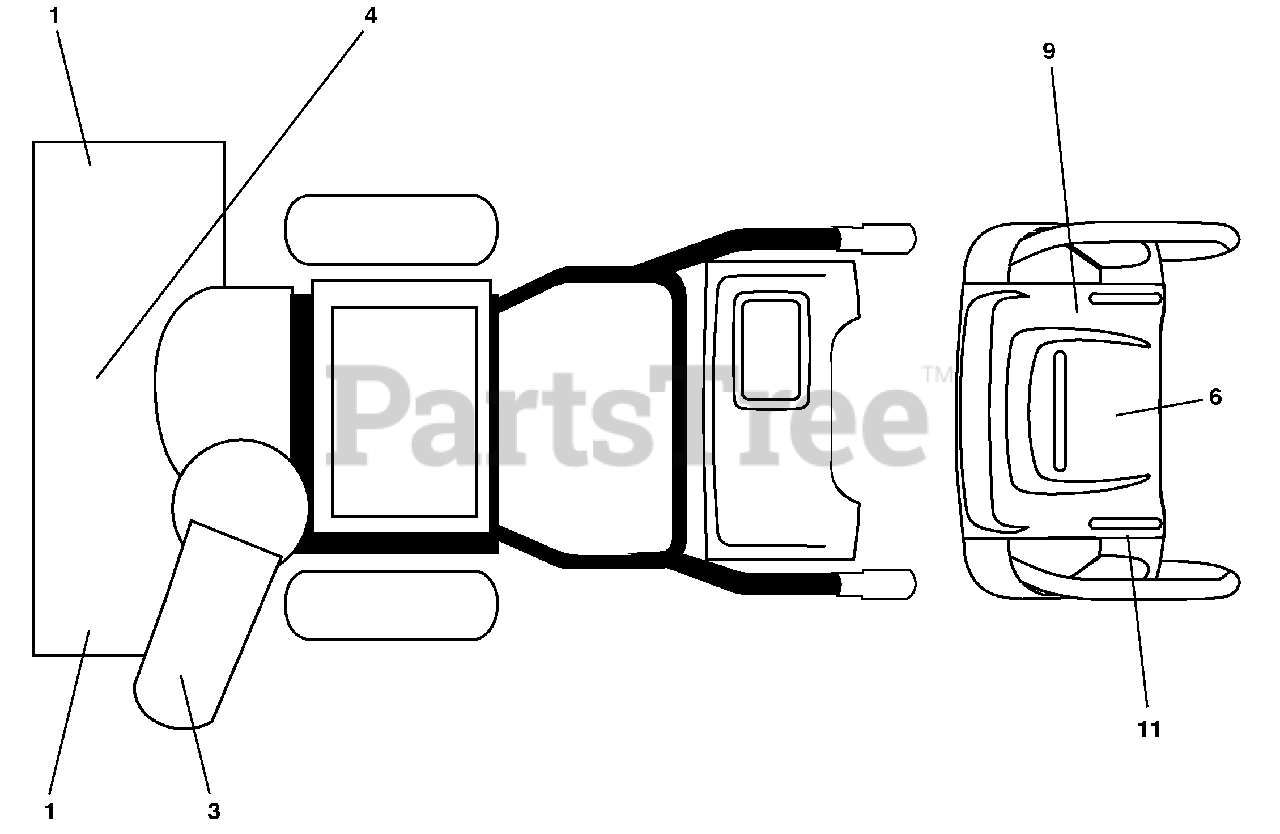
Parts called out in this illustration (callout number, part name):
1	DECAL, DANGER
3	DECAL, DANGER, DEFLECTOR
4	DECAL, DANGER
6	DECAL, INSTRUCTION
9	DECAL, CONS RT SPD/LEV/PWST
11	DECAL, CONS LT W/O DEFLECTOR
11	OWNER'S MANUAL, ENGLISH
11	OWNER'S MANUAL, FRENCH
